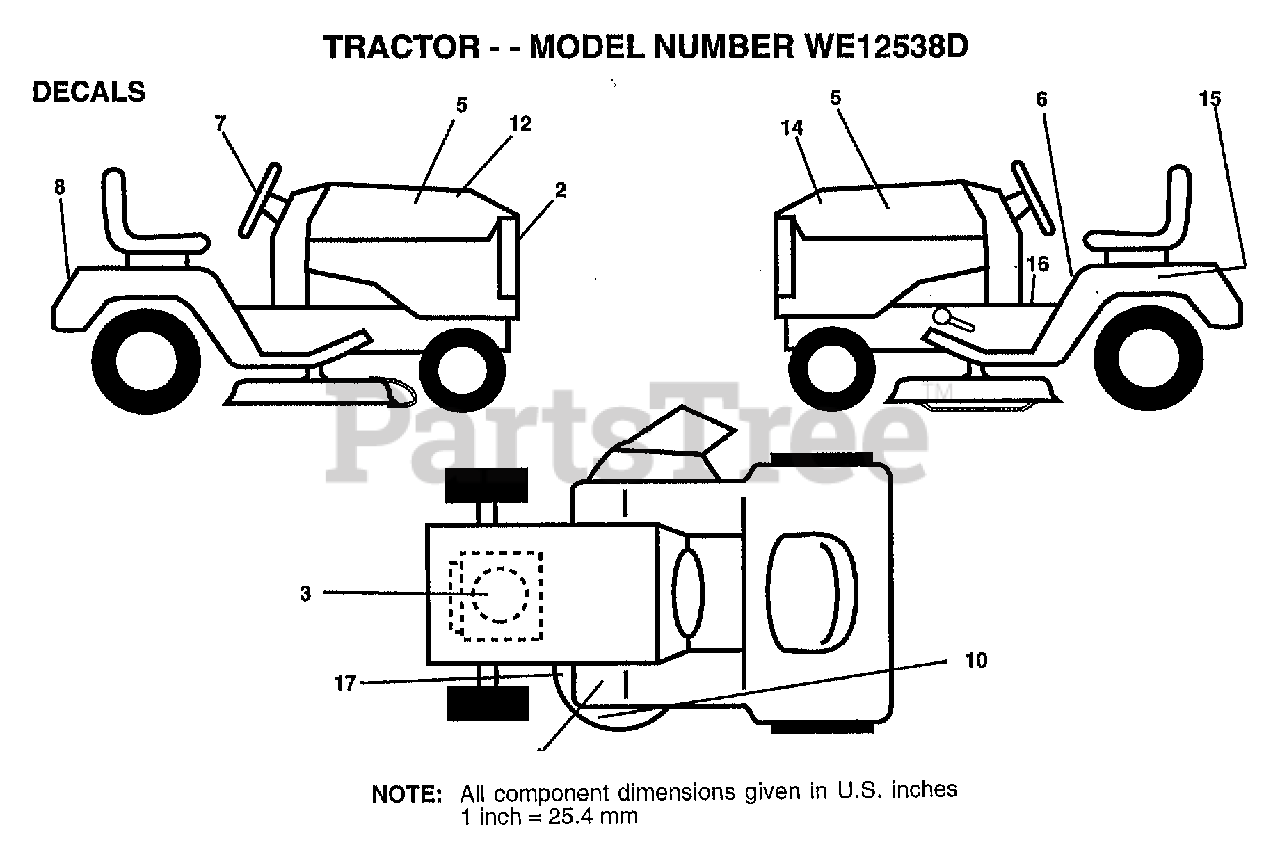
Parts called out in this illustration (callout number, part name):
2	"DECAL GRILLE,LENS"
3	DECAL, HP ENGINE
5	"DECAL.PANEL,SIDE"
6	"DECAL DANGER,FEND"
7	"DECAL INS,STRG WH"
8	DECAL-FENDER
9	DECAL CHASSIS SPEED DECK
11	DECAL.DANGER.CUTF
12	"DECAL HOOD,RH"
14	DECAL HOOD LH
15	DECAL.BATRY.3-3908
16	"DECAL DASH,OPER."
17	DECAL
18	DECAL.EURO.ST.CE.
